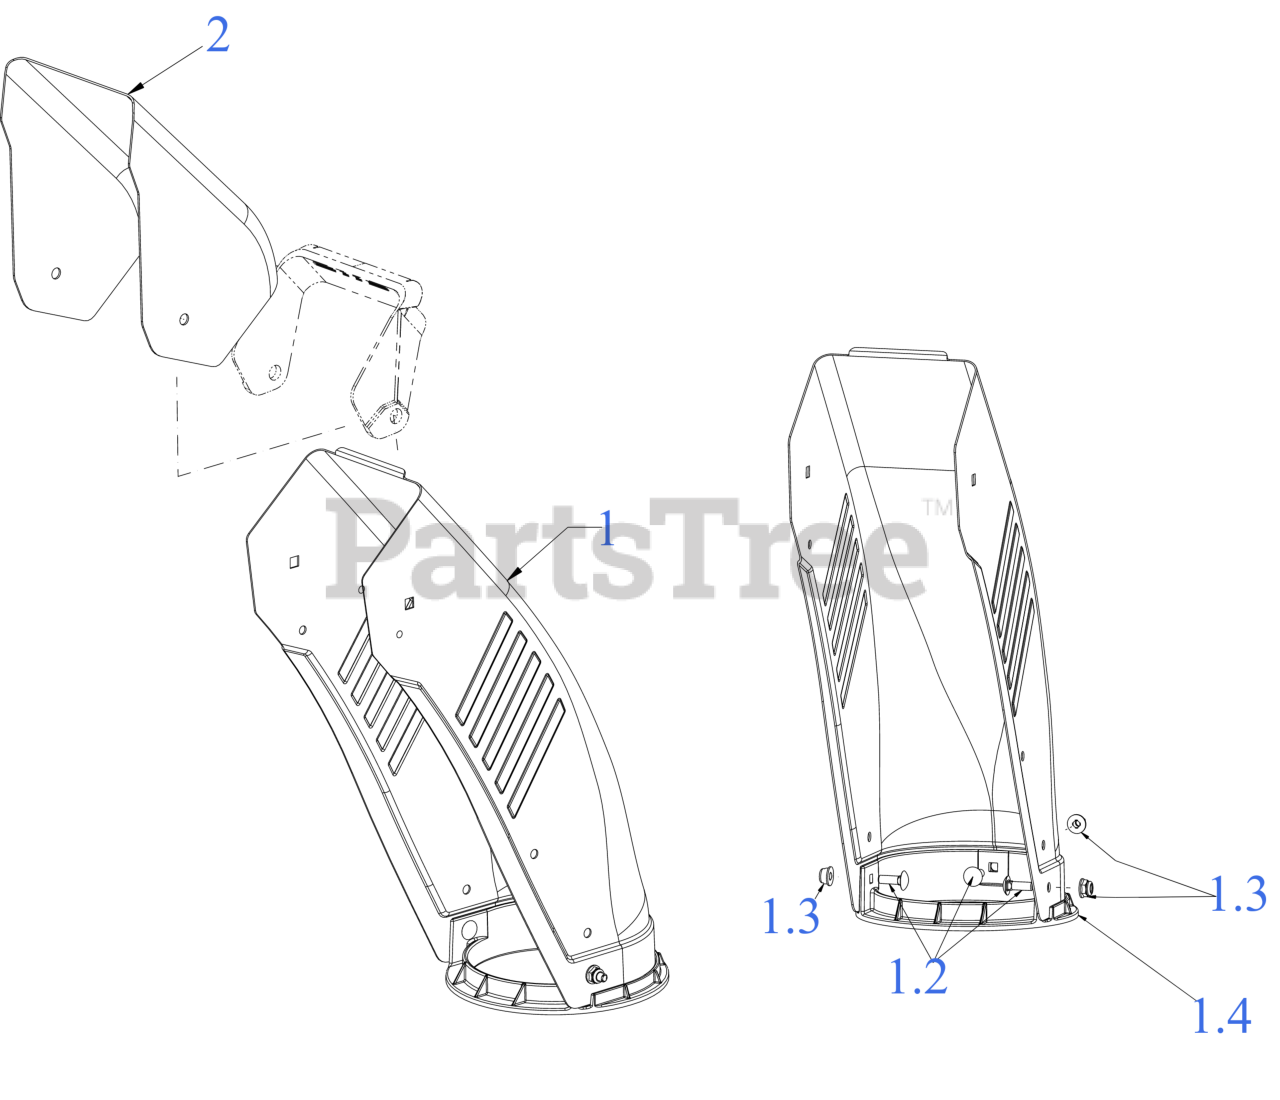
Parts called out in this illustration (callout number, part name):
1	STEEL CHUTE
1.2	SCREW 1/4-20 x .75 GR5
1.3	FLANGE LOCK NUT
1.4	CHUTE BASE 5.0 DIA
2	STEEL CHUTE (UPPER)
